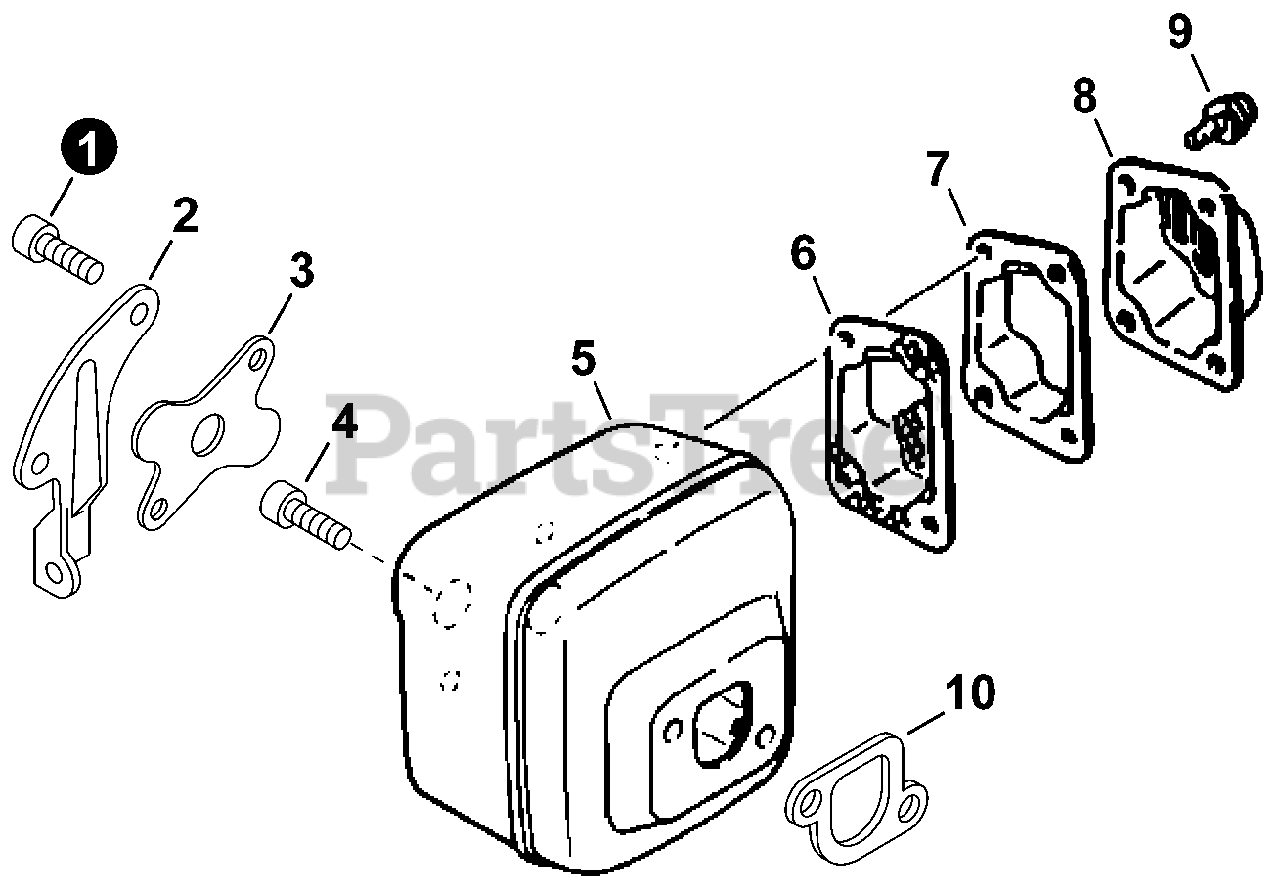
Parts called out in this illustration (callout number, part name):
1	BOLT 5x10
2	BRACKET, MUFFLER
3	COVER, MUFFLER
4	BOLT 6x20
6	SCREEN, SPARK ARRESTER
7	GUIDE, EXHAUST
8	OUTLET, EXHAUST
9	BOLT 4x10
10	GASKET, MUFFLER
